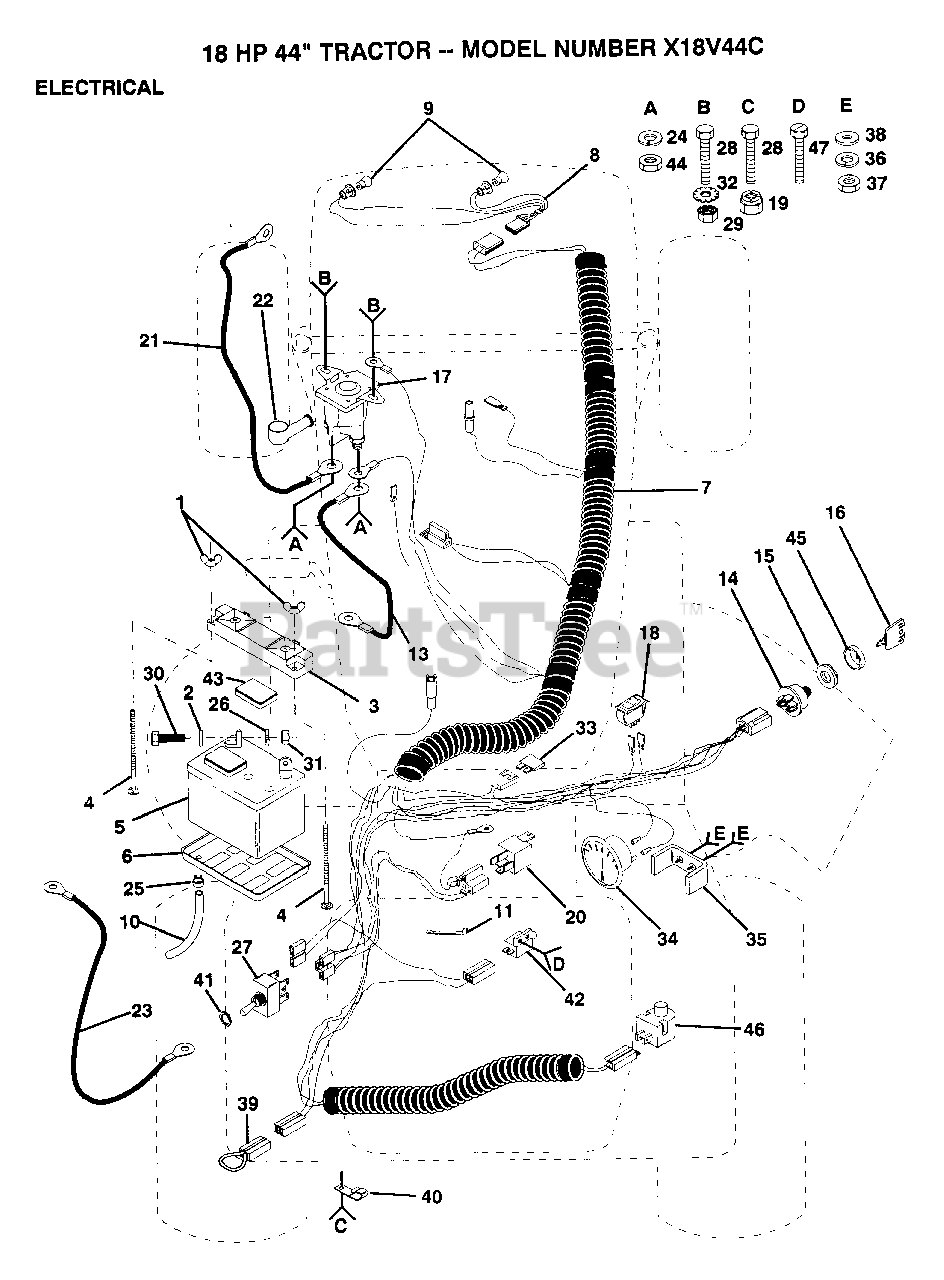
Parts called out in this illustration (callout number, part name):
2	WASHER
4	BOLT
6	"TRAY T, BATTERY"
7	IGNITION HARNESS
11	WIRE TIE
13	CABLE-BATTERY T
15	NUT IGNITION
16	KEY
18	SWITCH LT
20	RELAY ASSY T
21	"CABLE T, BATTERY"
23	CABLE T
25	HOSE CLAMP T
26	LOCKWASHER
28	BOLT
29	NUT
30	BOLT LT
33	FUSE HYT
34	AMMETER T
38	WASHER
40	CLIPT
41	HEX NUT T
42	SWITCH-INTER. GT
43	"CAP,BATTERY "
44	NUT
46	SWITCH SEAT
47	SCREW
